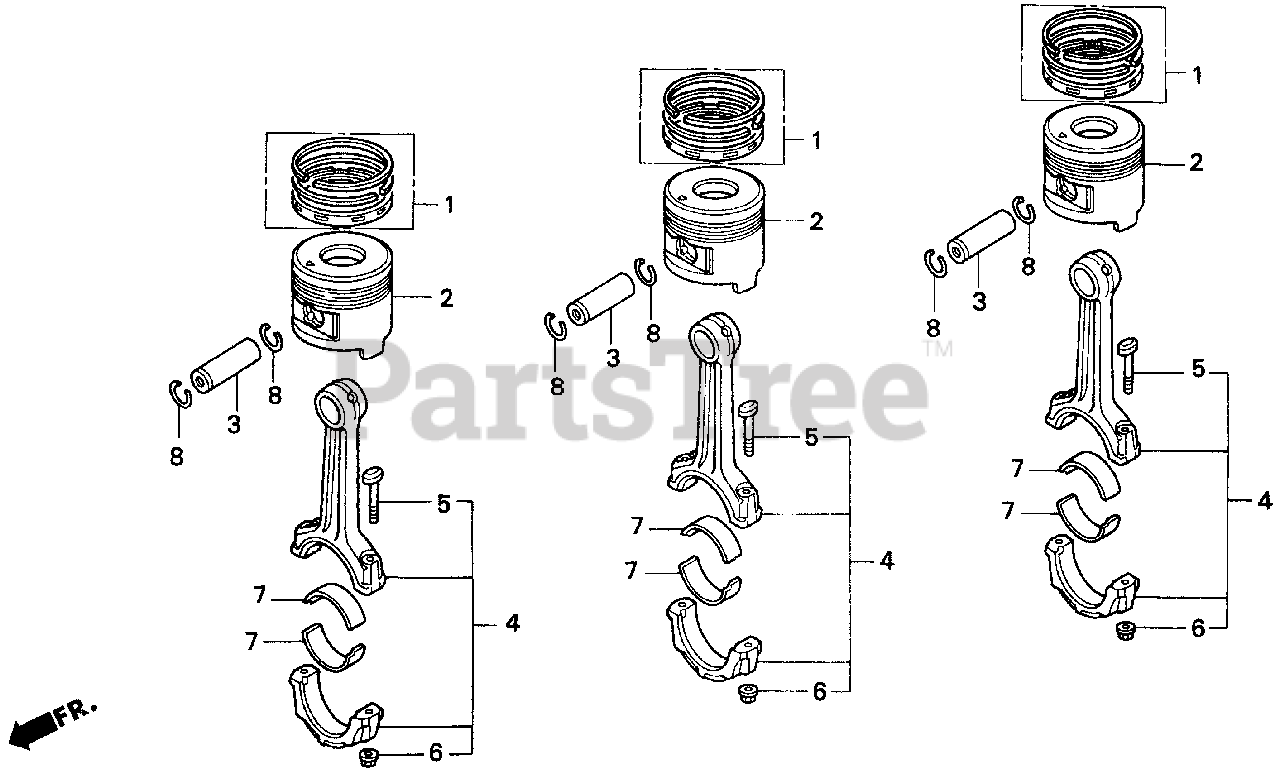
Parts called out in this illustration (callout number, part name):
1	RING SET, PISTON (STD)
1	RING SET, PISTON (OS 0.25)
1	RING SET, PISTON (OS 0.50)
2	PISTON (USA)
2	PISTON (OS 0.25)
2	PISTON (OS 0.50)
3	PIN, PISTON
4	ROD ASSY., CONNECTING
5	BOLT, CONNECTING ROD (8X51)
6	NUT, CONNECTING ROD
7	BEARING A, CONNECTING ROD (BLUE)
7	BEARING B, CONNECTING ROD (BLACK)
7	BEARING C, CONNECTING ROD (BROWN)
7	BEARING D, CONNECTING ROD (GREEN)
7	BEARING E, CONNECTING ROD (YELLOW)
7	BEARING, CONNECTING ROD (F)(PINK)
7	BEARING G, CONNECTING ROD (RED)
8	CLIP, PISTON PIN
